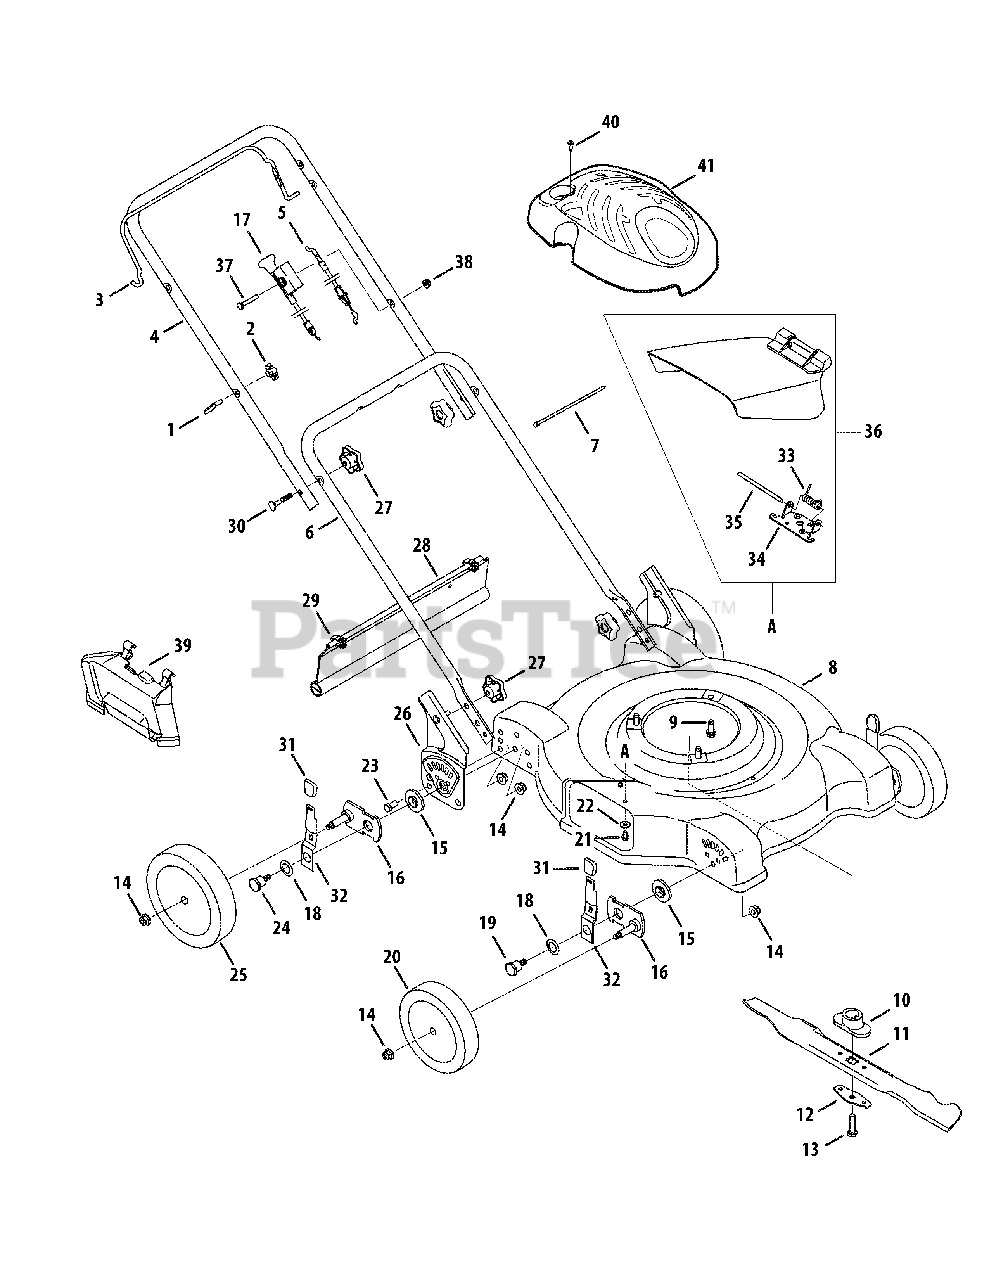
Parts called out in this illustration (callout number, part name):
1	Eye Bolt
2	Wing Nut
5	Control Cable
7	Cable Tie
9	TT Screw, 3/8-16 x 1.0
10	Blade Adapter
11	Standard Blade, 22"
11	Mulching Blade, 22"
12	Blade Bell Support
13	Screw, 3/8-24 x 1.5
14	Lock Nut, 3/8-16
15	Height Adjuster Bearing
16	Pivot Arm
17	Choke Cable
18	Bell Washer, .760 OD x 1.25 OD
19	Shoulder Screw
20	Front Wheel, 7 x 1.8, Bar
21	TT Screw, 1/4-20 x .5
22	Bell Washer, .265 ID x .75 OD
23	Screw, 3/8-16 x .75
24	Shoulder Screw
25	Rear Wheel, 8 x 1.8, Bar
27	Star Knob
28	Trailshield
29	Hinge Clip
30	Carriage Bolt, 5/16-18 x 2
31	Knob
32	Lever
33	Torsion Spring
34	Chute Hinge
35	Hinge Pin
36	Hinged Chute Deflector Assembly
37	Screw, 1/4-20 x 1.50
38	Nut, Flange Lock, 1/4-20
39	Mulching Baffle
40	Screw, Machine, M4-.7
41	Engine Shroud
